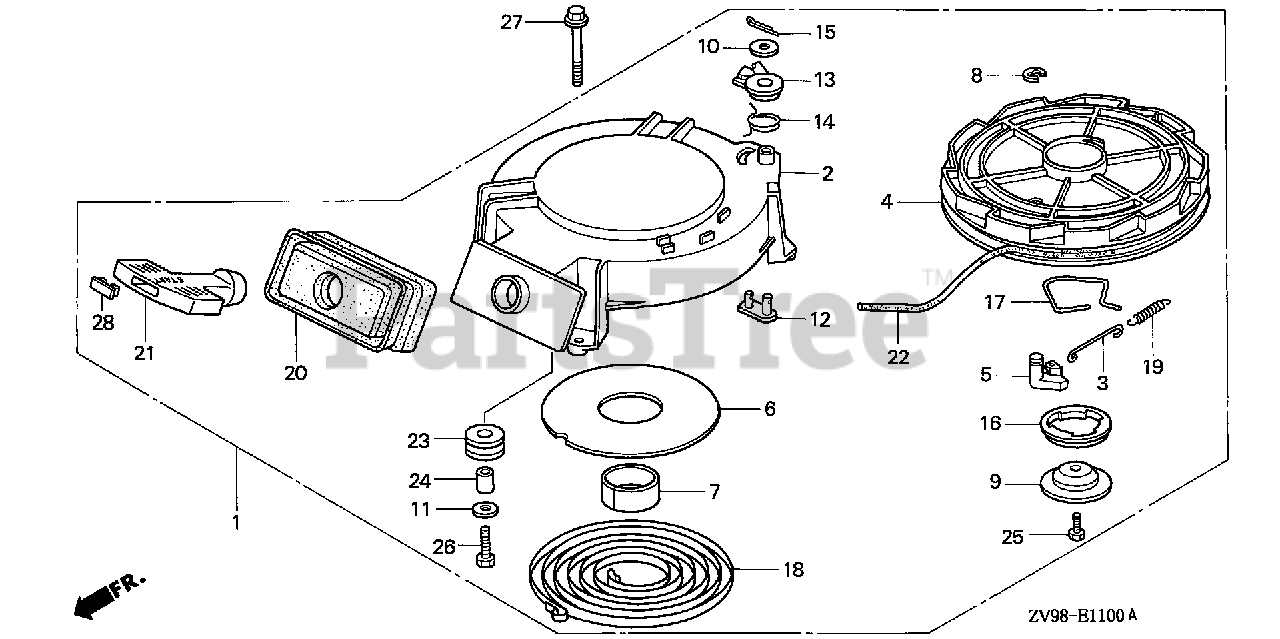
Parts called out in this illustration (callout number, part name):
1	STARTER ASSY., RECOIL
2	CASE, RECOIL STARTER
3	GUIDE, RECOIL STARTER
4	PULLEY, RECOIL STARTER
5	RATCHET, STARTER
9	PLATE, FRICTION
11	WASHER, THRUST
12	STOPPER, REEL
13	ARM, STOPPER
14	SPRING, STOPPER
15	PIN, SPLIT
17	SPRING, FRICTION
18	SPRING, RECOIL STARTER
19	SPRING, RETURN
20	SEAL, RECOIL
21	GRIP, STARTER
22	ROPE, RECOIL STARTER (NA USE ALT:08560-ZG921-11)
23	ROLLER, STARTER
24	GUIDE, ROLLER
25	BOLT (6X20)
26	BOLT, HEX. (6X14)
27	BOLT, FLANGE (6X22)
